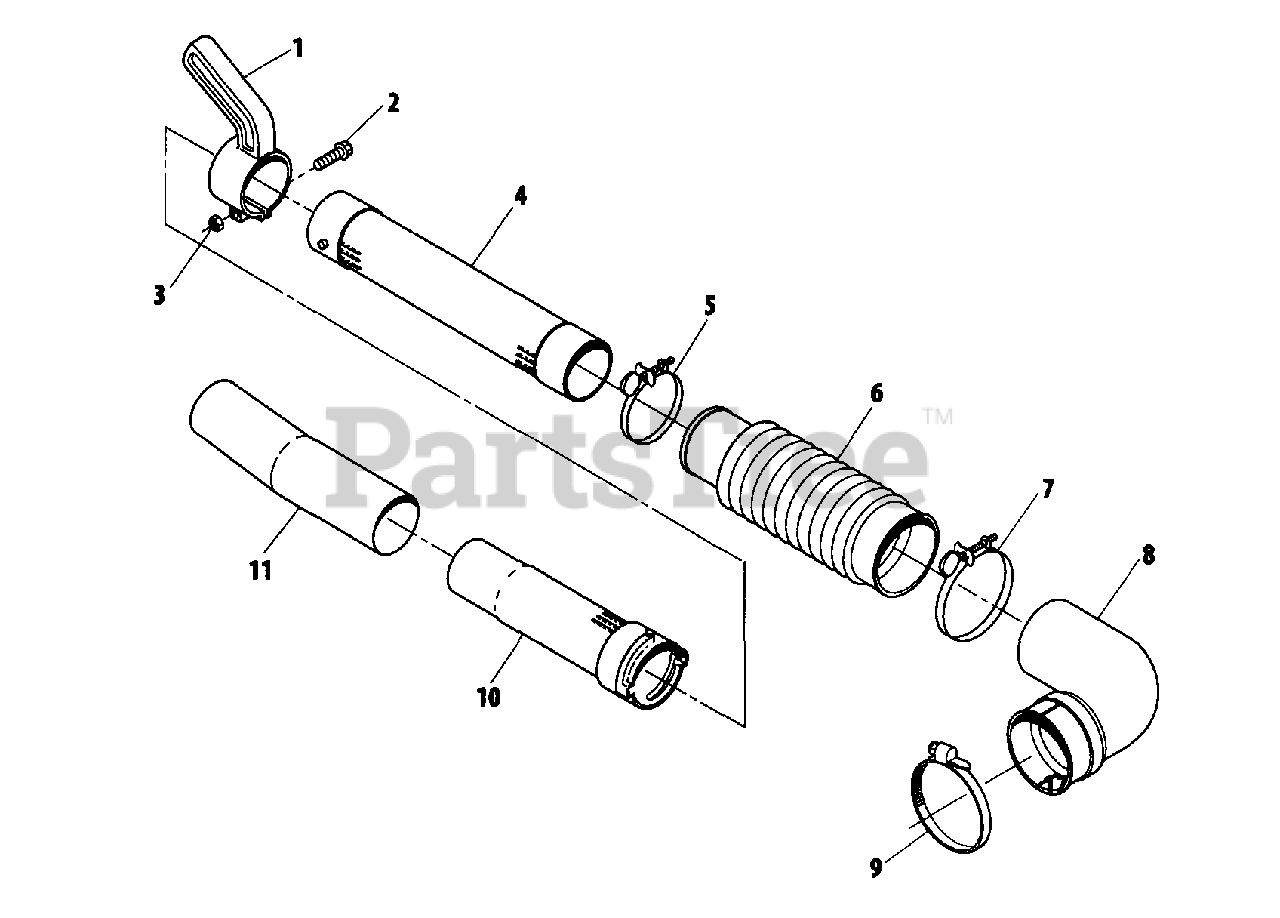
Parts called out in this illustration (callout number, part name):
1	HANDLE
2	SCREW - 6X40
3	NUT - 6
4	TUBE A
5	CLAMP
6	FLEXIBLE TUBE
7	CLAMP
8	TUBE, BLOWER - ELBOW
9	CLAMP
10	TUBE B
11	NOZZLE
